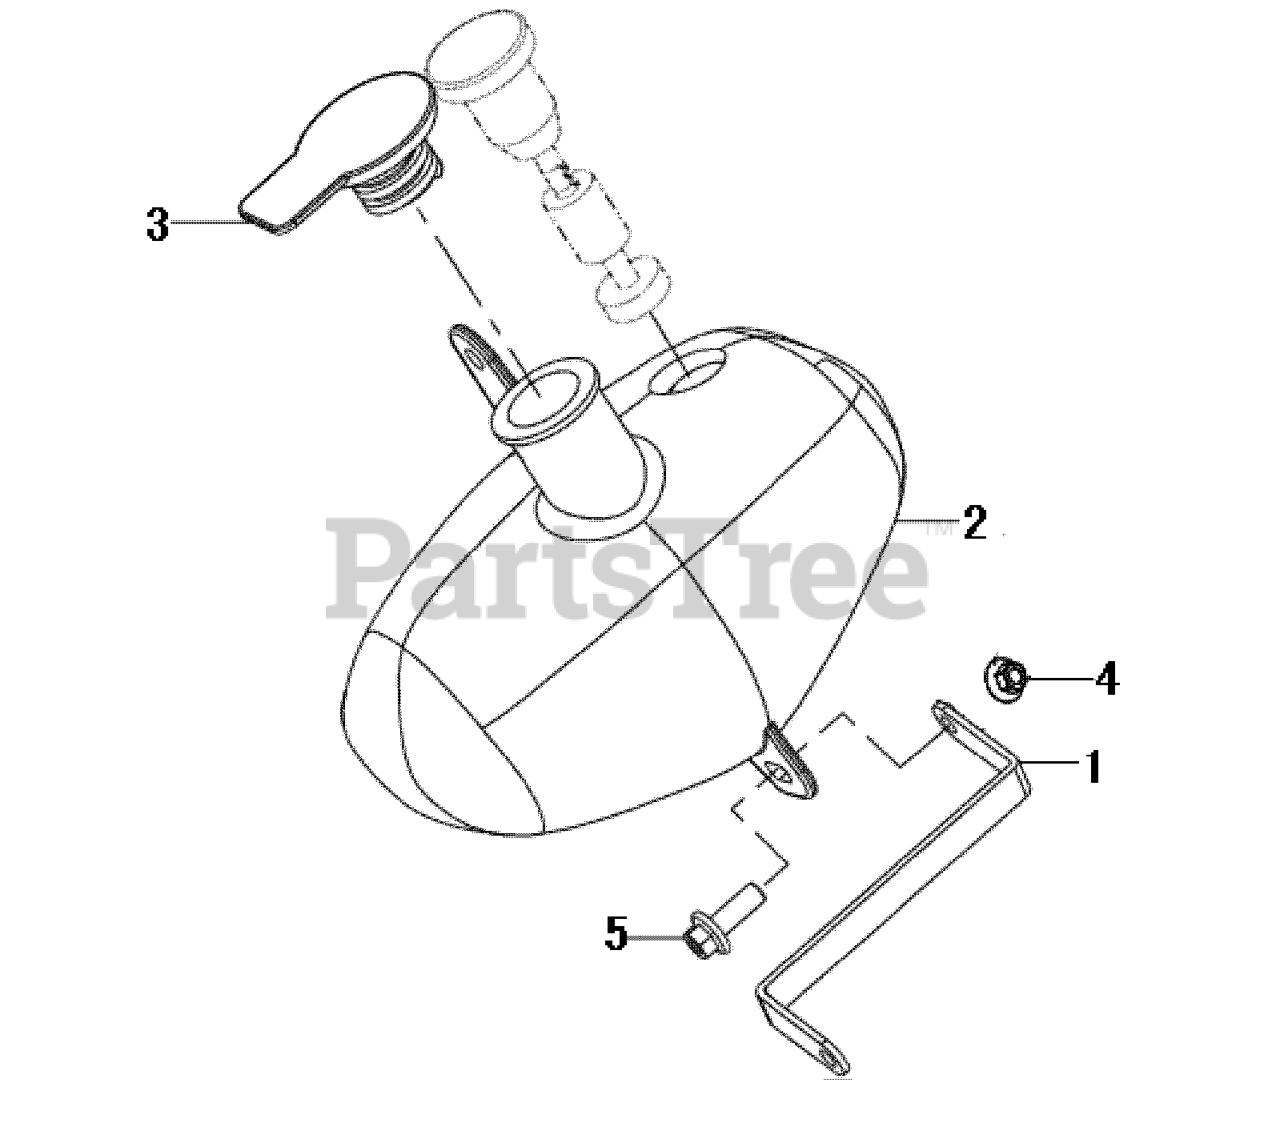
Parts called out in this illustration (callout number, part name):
1	BRACKET, OIL TANK MOUNTING
2	OIL TANK
3	CAP, OIL TANK
5	SCREW W/WASHER
